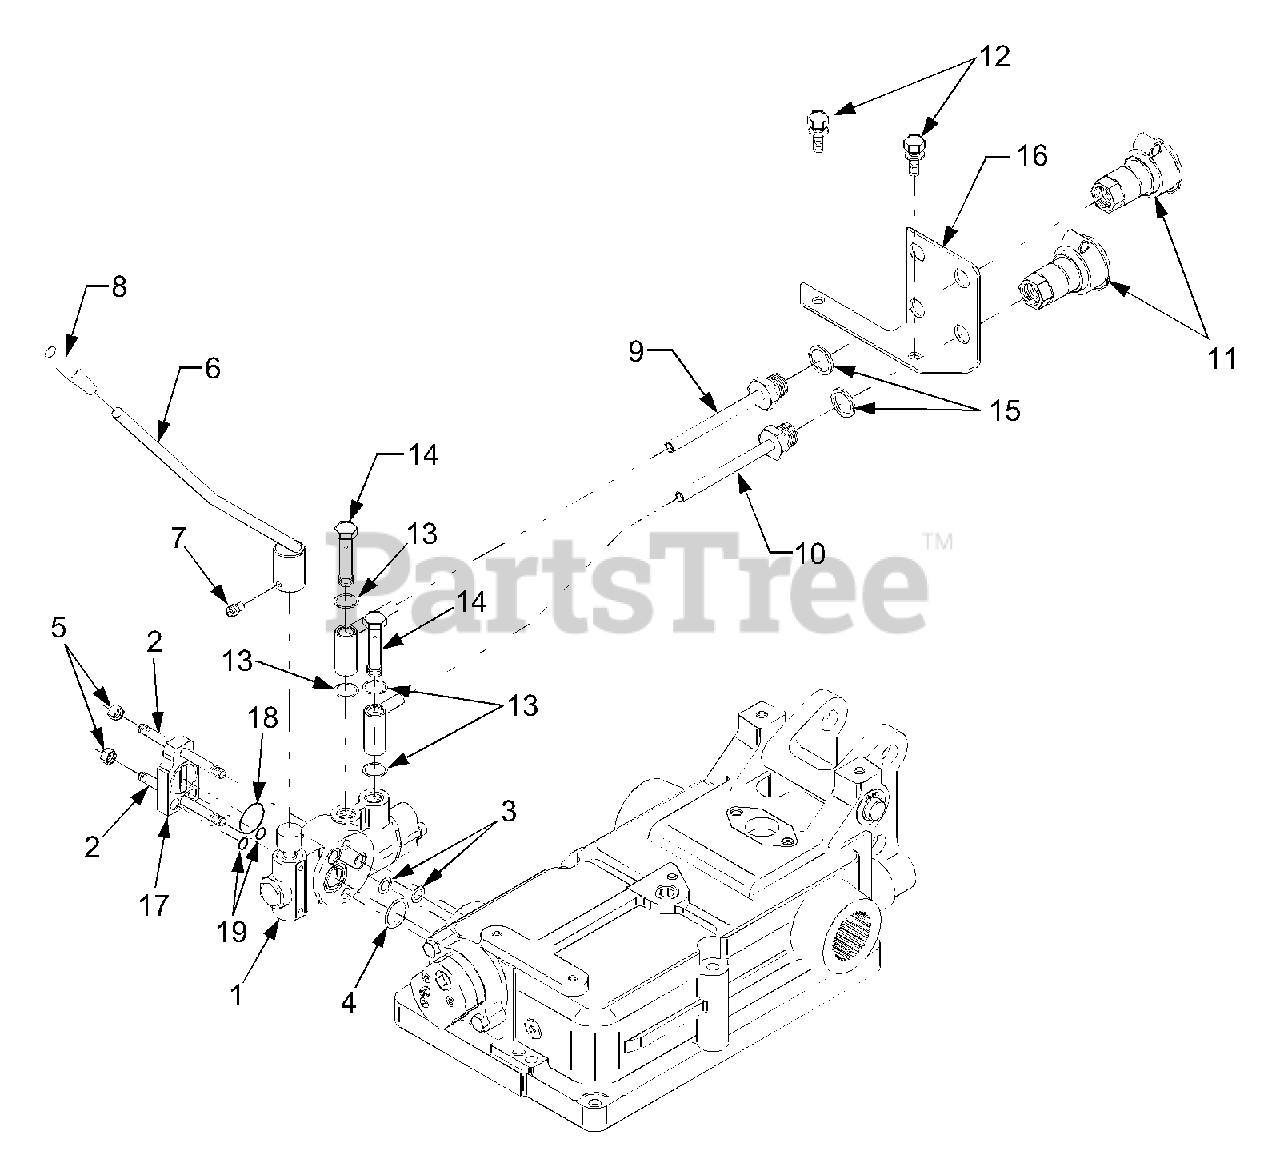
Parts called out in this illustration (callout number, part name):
1	Double Acting Valve (Detent)
6	Lever 3, Double Acting
8	Grip, Lever
9	Pipe A, Hydraulic
10	Pipe B, Hydraulic
11	Coupler Socket Ass'y
14	Bolt 2, Joint
16	Bracket, Sooket
